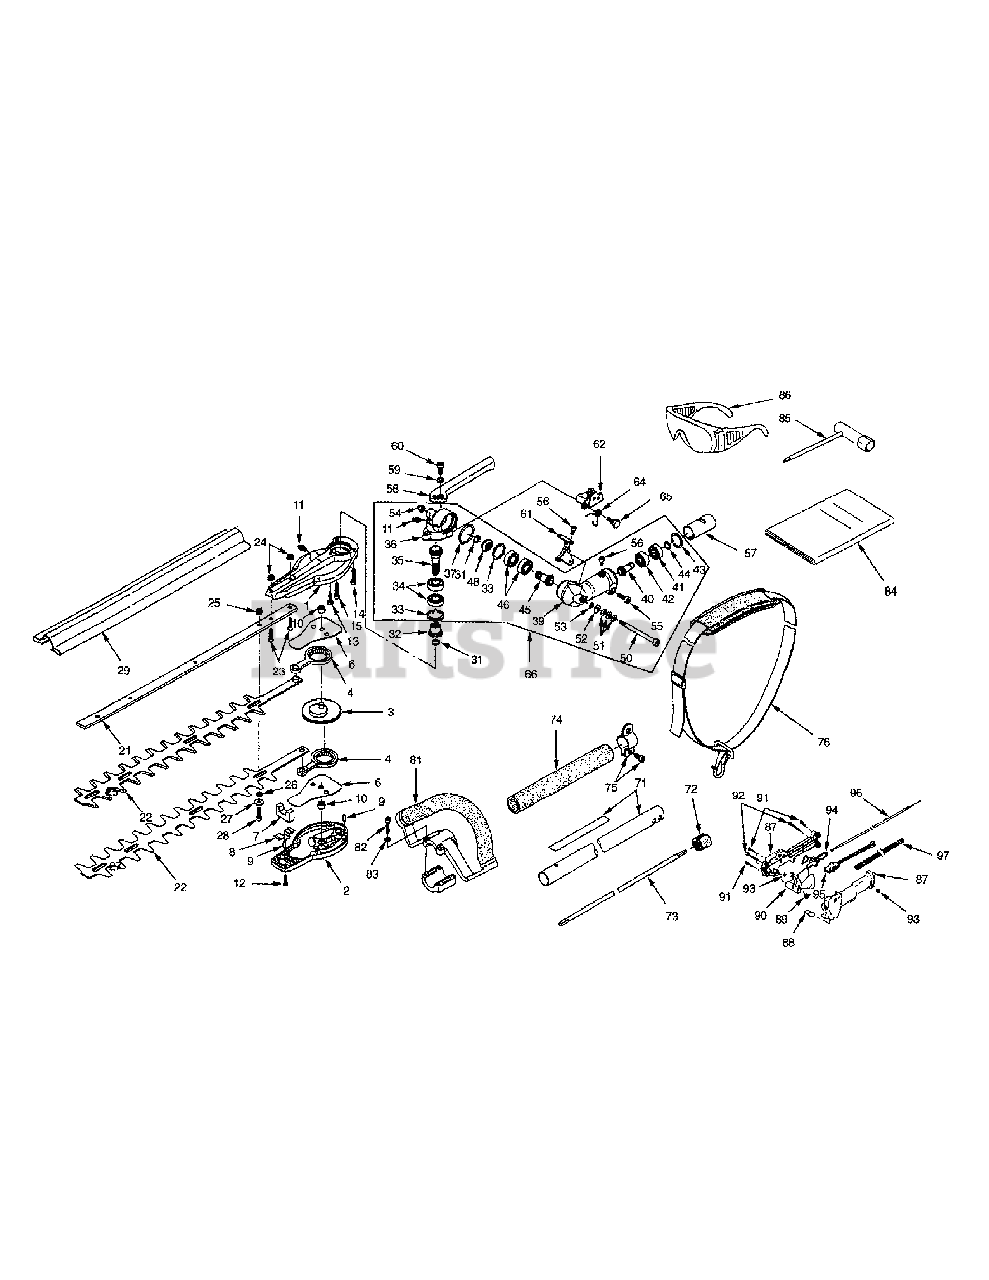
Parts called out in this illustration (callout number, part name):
10	Bearing, Needle
11	Nipples, Grease
23	Screw, M5x20
29	Cover, Blade
31	Snap Ring, S-10
32	Gear, Pinion
33	Snap Ring, R-28
34	Bearing, Ball, 6001L
37	O-Ring, 5-34
40	Gear, Pinion
41	Bearing, Ball, 6000ZZ
42	Bearing, Ball, 6000
43	Snap Ring, R-26
44	Snap Ring, S-10
45	Gear, Pinion
46	Bearing, Ball, 6001
59	Spring Washer
66	Case Assembly, Gear
71	Pipe Complete
73	Shaft, Drive
76	Harness, Shoulder
81	Handle Assembly
84	Manual, Operator's
85	Spanner, Box
86	Goggle
87	Lever Assembly, Throttle
92	Screw, M5x30
95	Stop, Switch
96	Wire, Throttle
97	Hose
